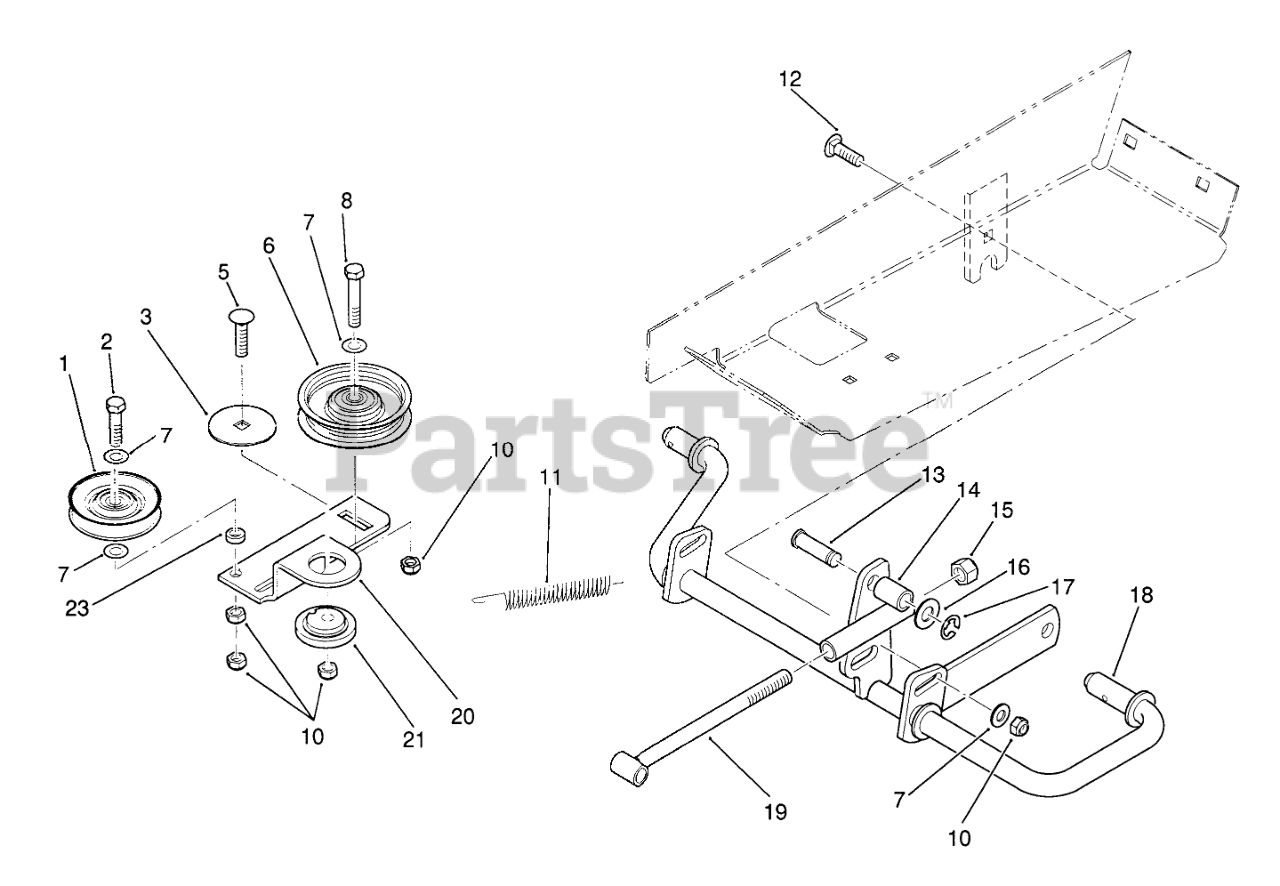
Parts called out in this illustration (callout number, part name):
1	Pulley
2	BOLT
3	WASHER-BEARING
5	Bolt
6	Idler Pulley
7	Washer
8	Bolt
10	NUT
11	SPRING - CLUTCH
12	Bolt
15	Nut
16	Washer
17	E Ring
18	Shaft-W.A.
20	ARM-IDLER
21	BUSHING
23	SPACER
